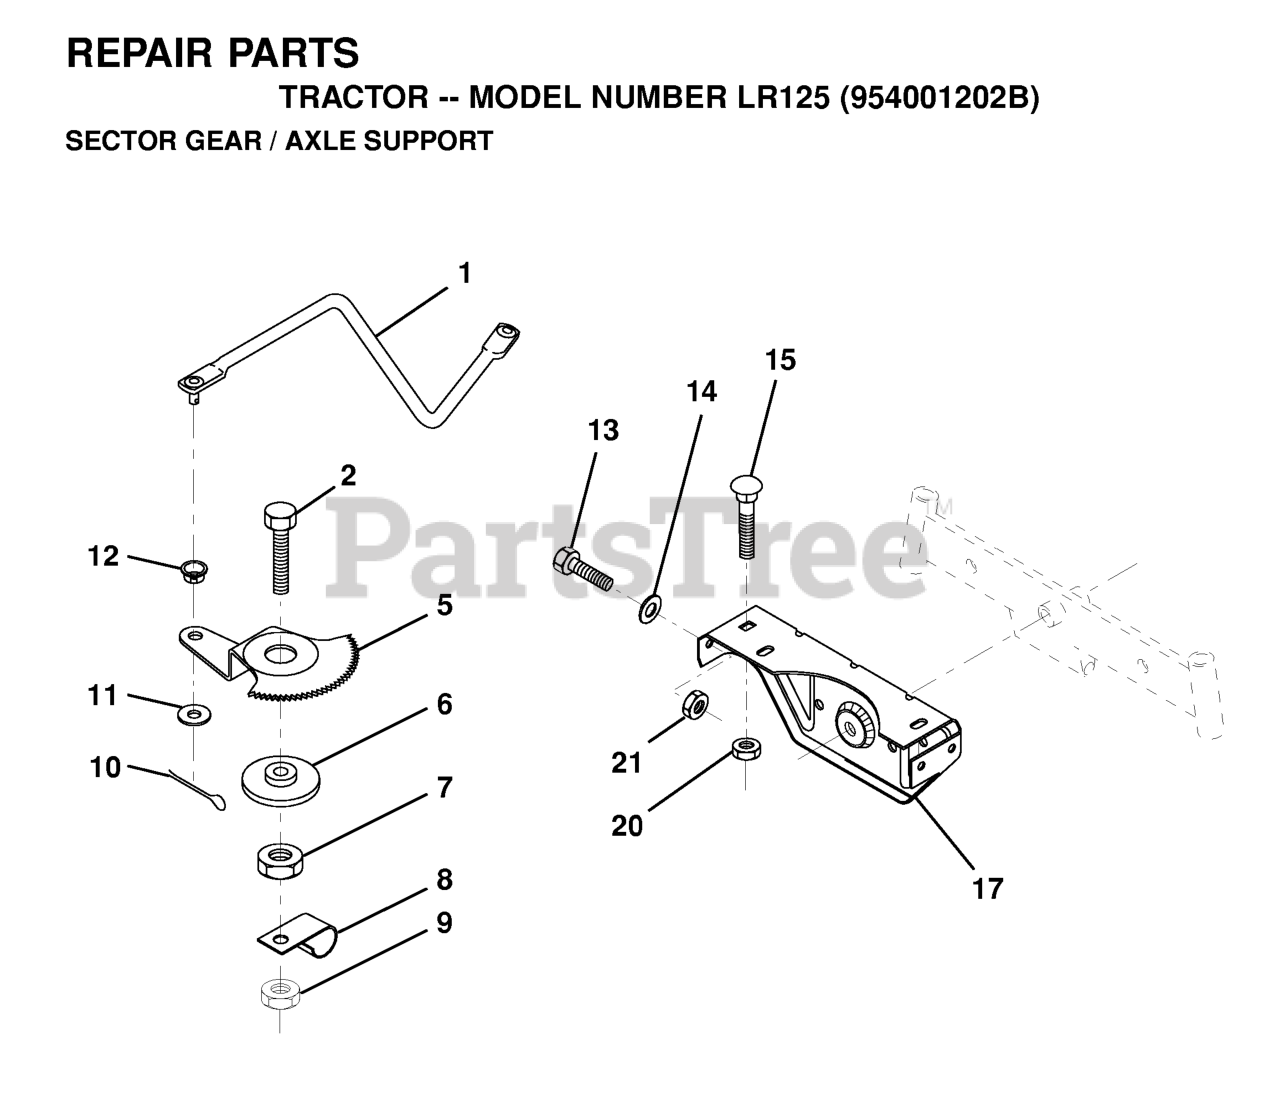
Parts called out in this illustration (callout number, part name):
5	GEAR SECTOR
7	NUT
8	CLIP INSULATOR
9	NUT LTV
10	COTTER PIN
11	WASHER
12	BUSHING.DRAGLINK (2 2)
13	BOLT
14	WASHER
17	SUPPORT/AXLE FRONT
21	LOCKNUT
